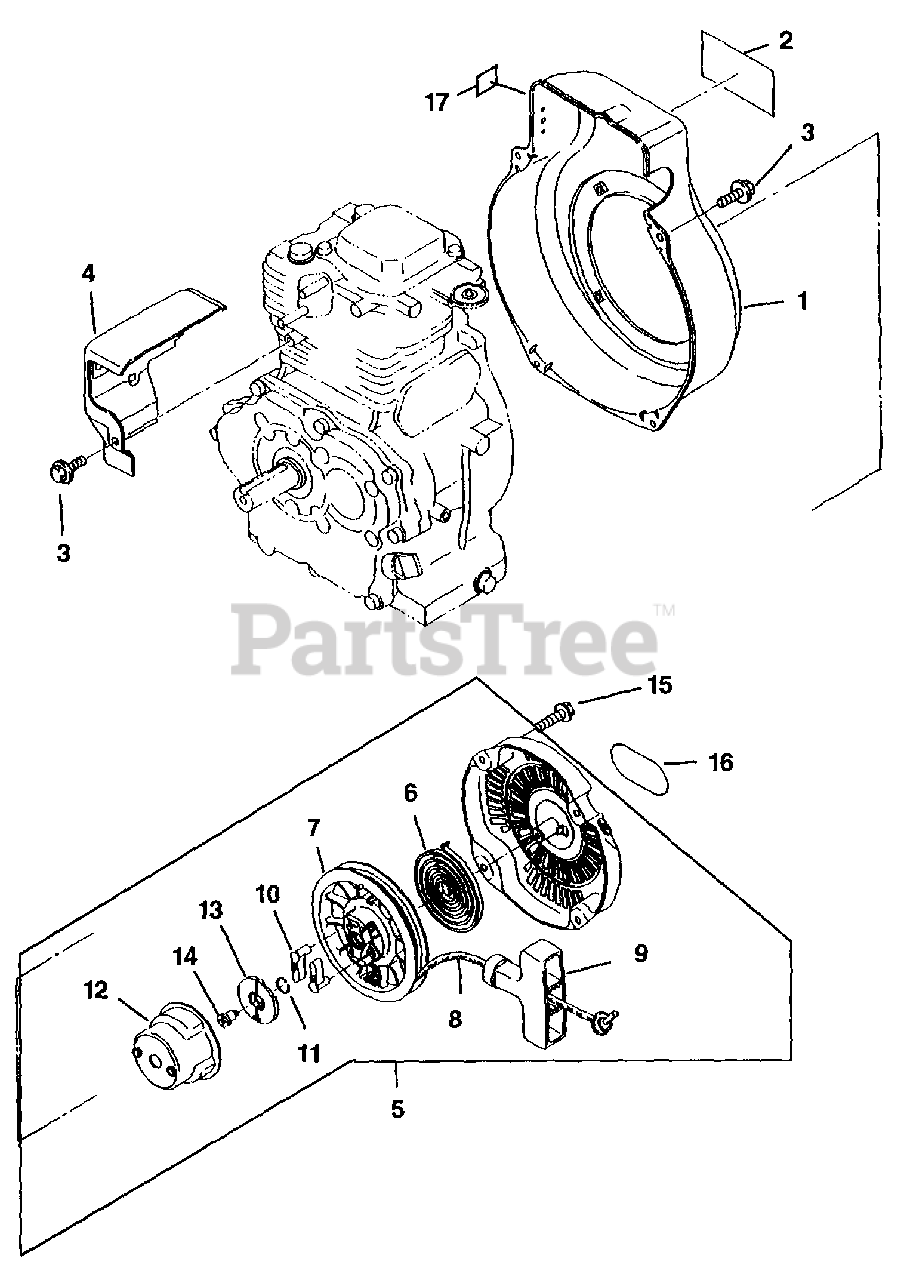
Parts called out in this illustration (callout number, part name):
1	Blower Hsg - LRX4500
3	Flange bolt M6 x 12
4	Head cover
5	Recoil starter
6	Spiral spring
8	Starter rope
9	Starter knob
11	Friction spring
12	Starter pulley
13	Ratchet guide
14	Set screw
15	Flange bolt M6 x 8
16	Label, OHV
17	Switch Label
